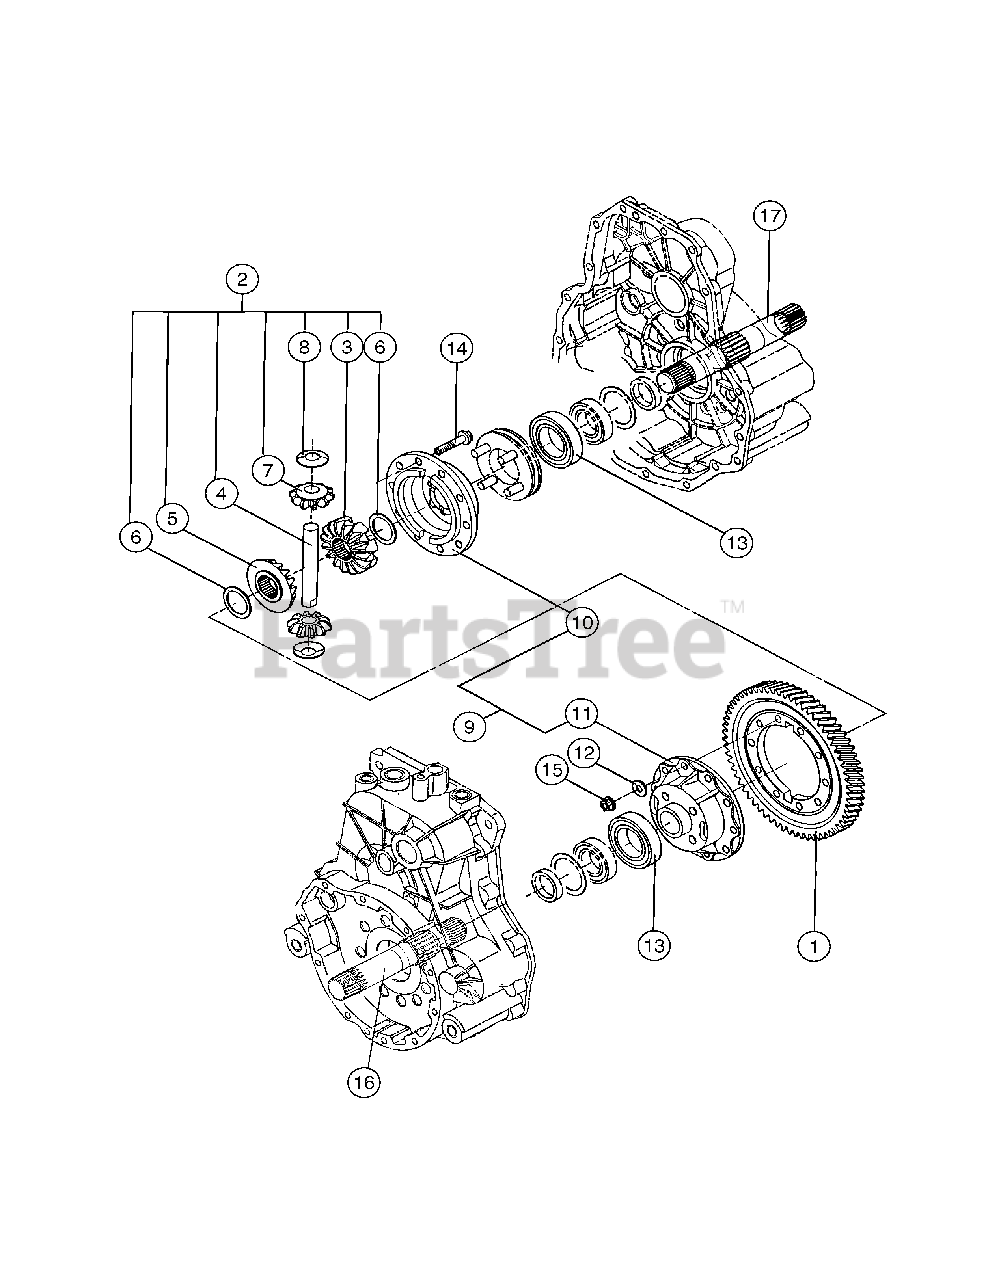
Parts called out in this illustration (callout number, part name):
1	Gear, 63H, Final
2	Differential, Gear Kit
3	Gear (RR, Differential)
4	Shaft, Differential Pinion
5	Differential Side Gear, RH
6	Washer, Differential Gear
7	Pinion, Differential
8	Washer, Differential Pinion
9	Differential, Case Kit
10	Case (R, Differential)
11	Case (L, Differential)
12	Washer, 8
13	Bearing, 6008
14	Bolt, 8 x 40
15	Nut, 8
